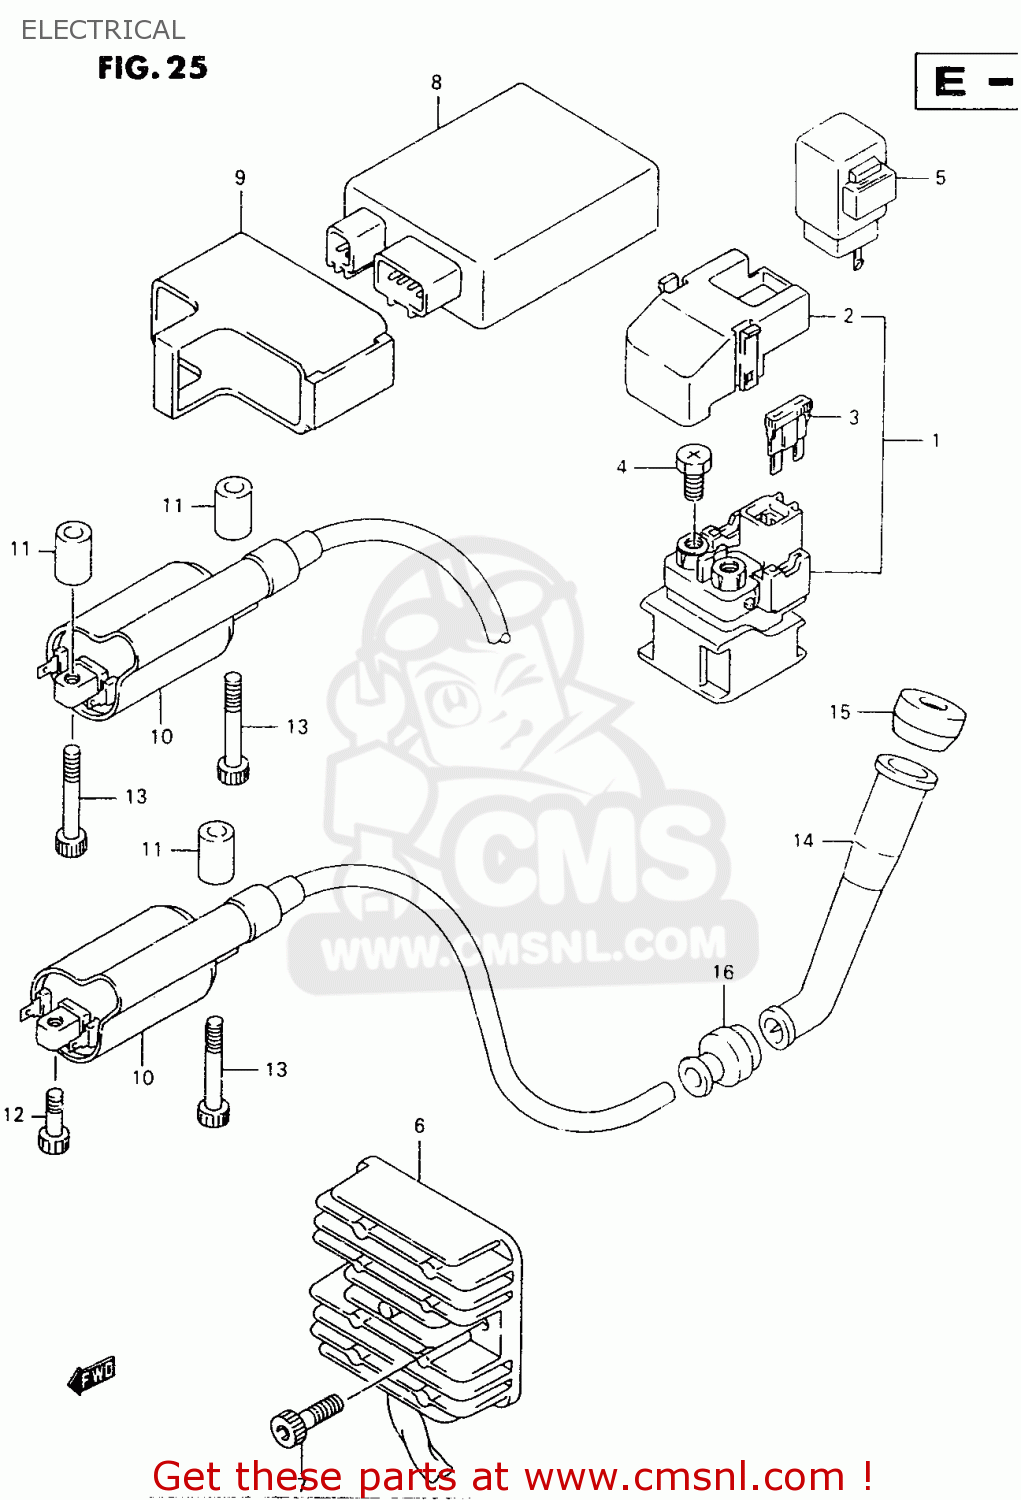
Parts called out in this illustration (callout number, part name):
1	RELAY ASSY,STARTING MOTOR
2	COVER,RELAY ASSEMBLY
3	FUSE(30A)
4	SCREW(6X8)
5	CONTROL UNIT,STG MOT RLY
6	RECTIFIER ASSY
7	BOLT,OIL FILLE
8	IGNITOR ASSY
9	CUSHION,IGNITOR
10	COIL ASSY,IGNITION
11	SPACER(6.2X12X16)
12	BOLT
13	BOLT
14	CAP,SPARK PLUG
15	SEAL,SPARK PLUG CAP
16	SEAL,HIGH TENSION CORD
